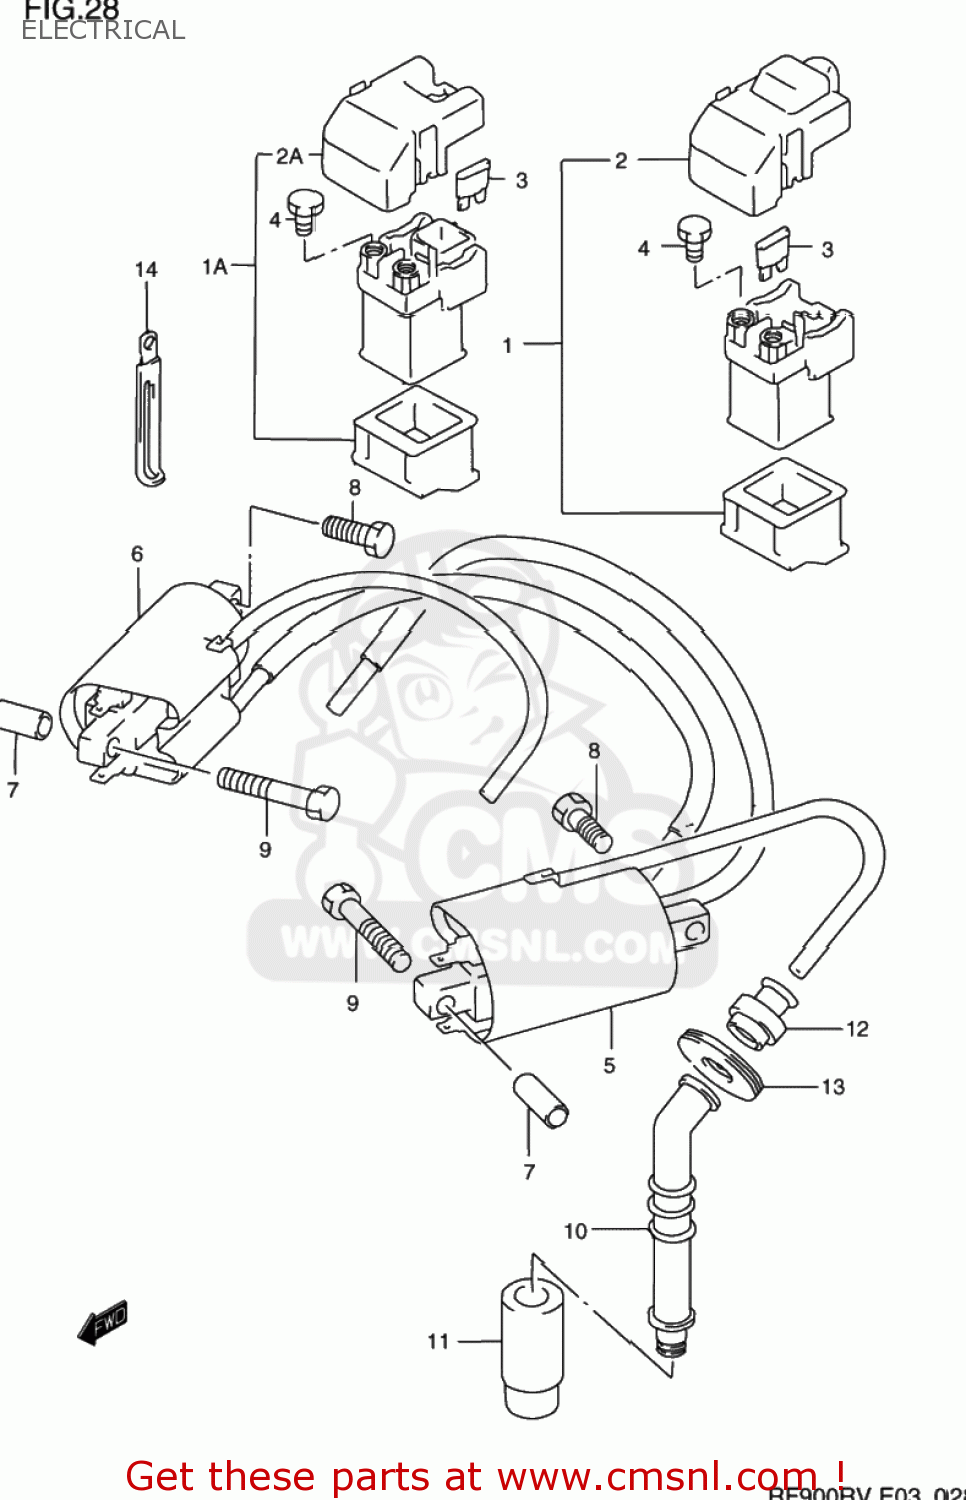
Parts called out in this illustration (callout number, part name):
1	RELAY ASSY,STARTING MOTOR
1A	RELAY ASSY,STARTING MOTOR
2	COVER,RELAY ASSEMBLY
2A	COVER,RELAY ASSEMBLY
3	FUSE(30A)
4	SCREW(6X8)
5	COIL ASSEMBLY,IGNITION NO
6	COIL ASSEMBLY,IGNITION NO
7	SPACER(6.2X15.5X16.5)
8	BOLT
9	BOLT
10	CAP,SPARK PLUG
11	SEAL,SPARK PLUG
12	SEAL,HIGH TENSION CORD
13	COVER,SPARK PLUG CAP
14	CLAMP
